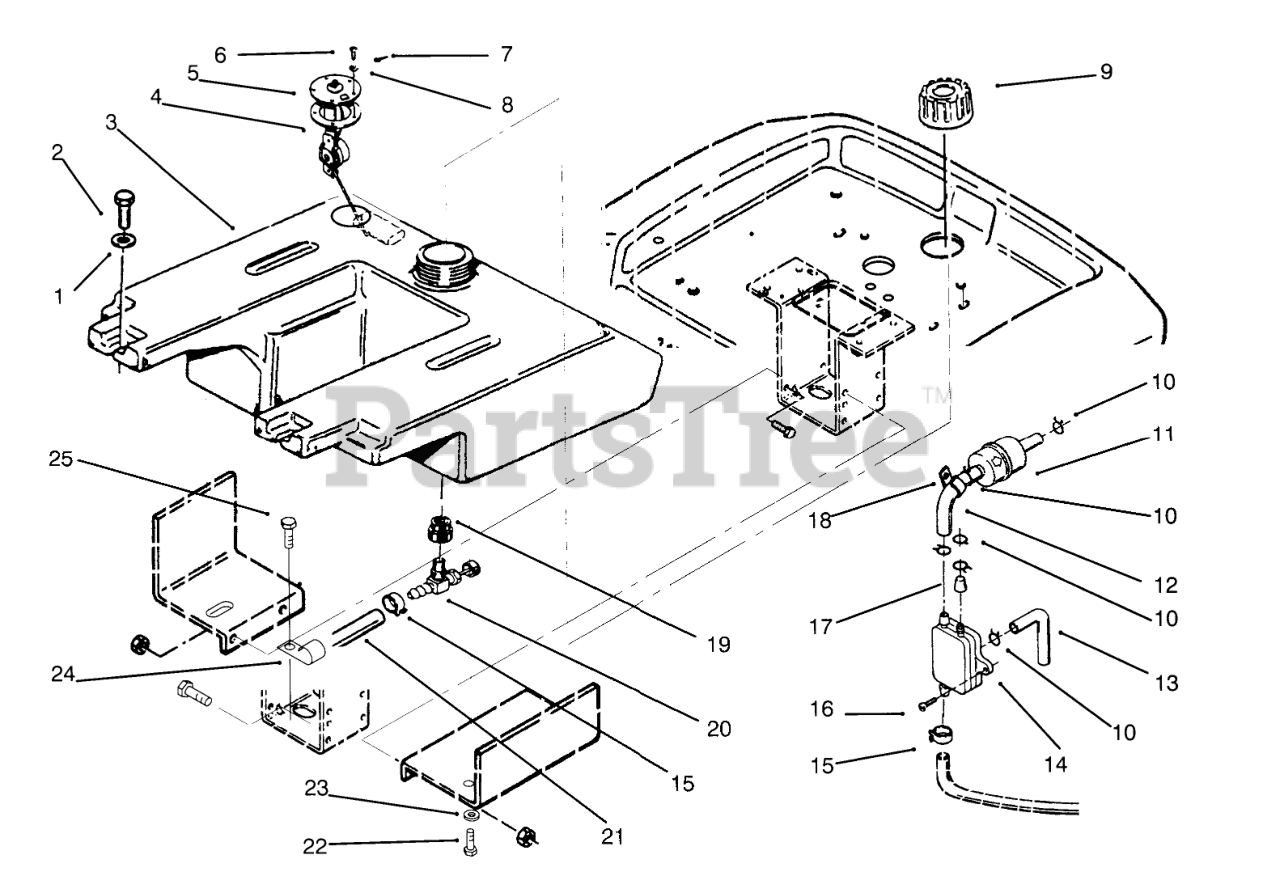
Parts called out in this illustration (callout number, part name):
1	WASHER-FLAT
3	Tank-Fuel (Incl. Ref.# 19 & 20)
4	GASKET-SENDER, FUEL
5	SENDER-FUEL LEVEL
6	Screw
7	TERMINAL-GROUND
8	WASHER-LOCK
9	GAS CAP ASM
10	CLAMP-HOSE
11	Filter-Fuel
12	Hose
13	Hose
14	Fuel Pump
15	Clamp
16	SCREW-TAPPING PAN HD
17	Cap
18	CLAMP
19	BUSHING
20	VALVE-FUEL
21	FUEL HOSE 75" OF 6554
22	SCREW-HH
23	WASHER-LOCK
24	Clip
25	SCREW-HH, LOCK
